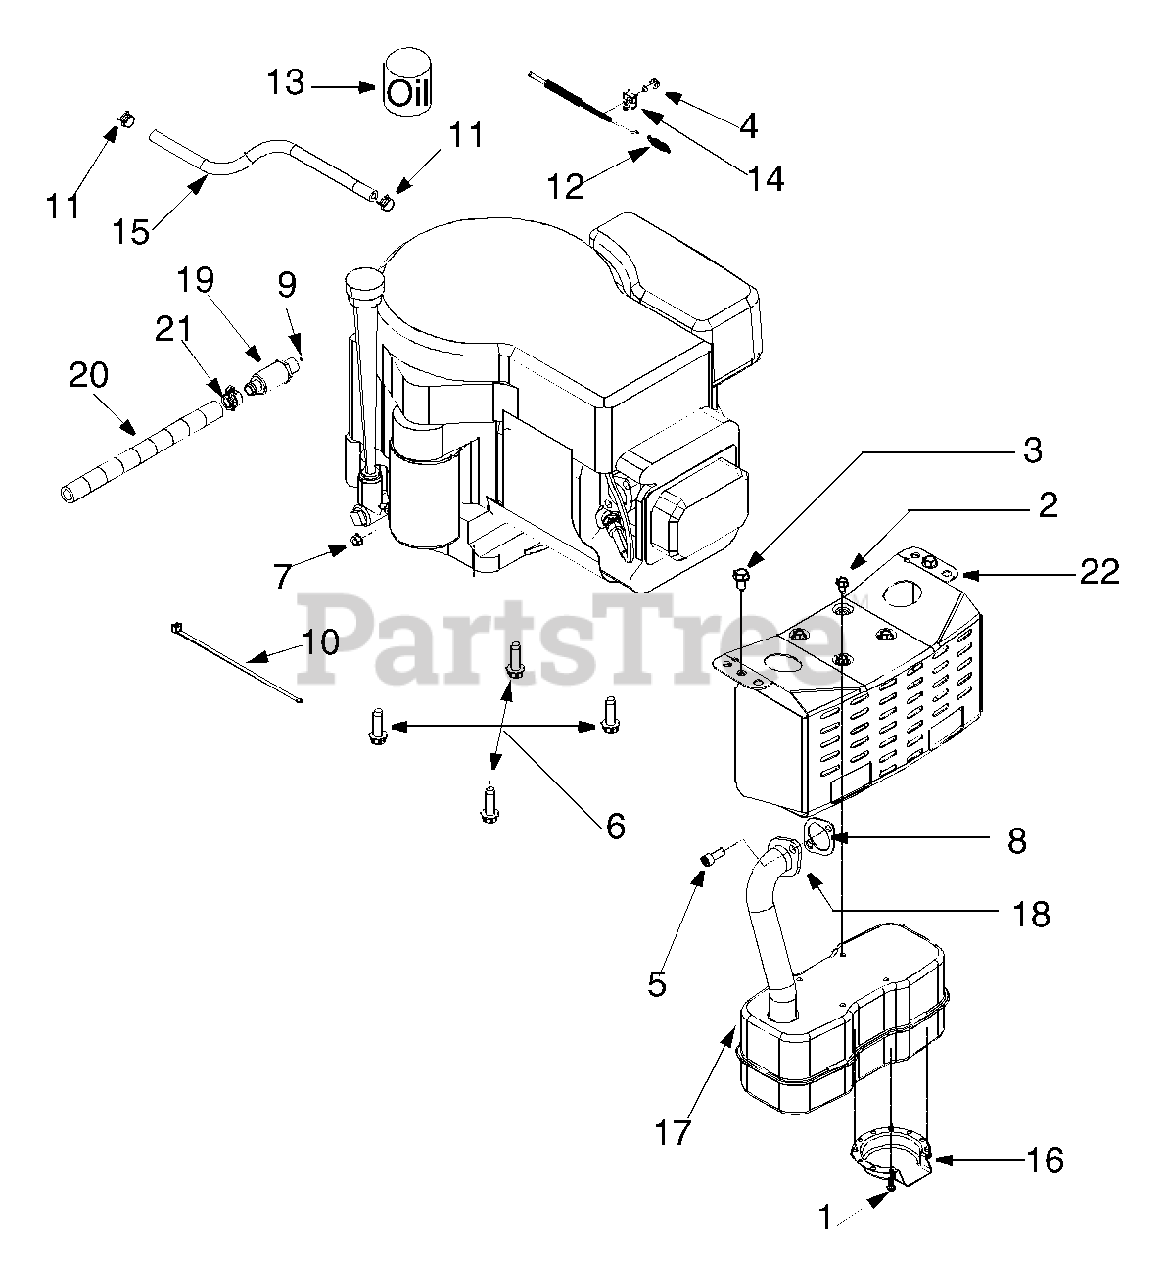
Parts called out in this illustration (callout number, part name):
1	AB Screw #8-18 x 0.5
2	TT Screw 1/4-20 x 0.5
3	AB Screw 5/16-12 x 0.5
4	T screw #10-32 x 0.625
5	Socket Hd Scr. 5/16-18 x.750
6	TT Screw 3/8-16 x 1.25
8	Exhaust Gasket
9	Sealant: Loctite(TM)
10	Cable Tie
11	Hose Clamp
12	Extension Spring
13	SAE 30W Oil
14	Throttle Clamp
15	Fuel Line Hose
16	Muffler Deflector
17	Muffler
18	Exhaust Pipe
19	Oil Drain
20	Oil Drain Extension Hose
21	Oil Drain Cap
